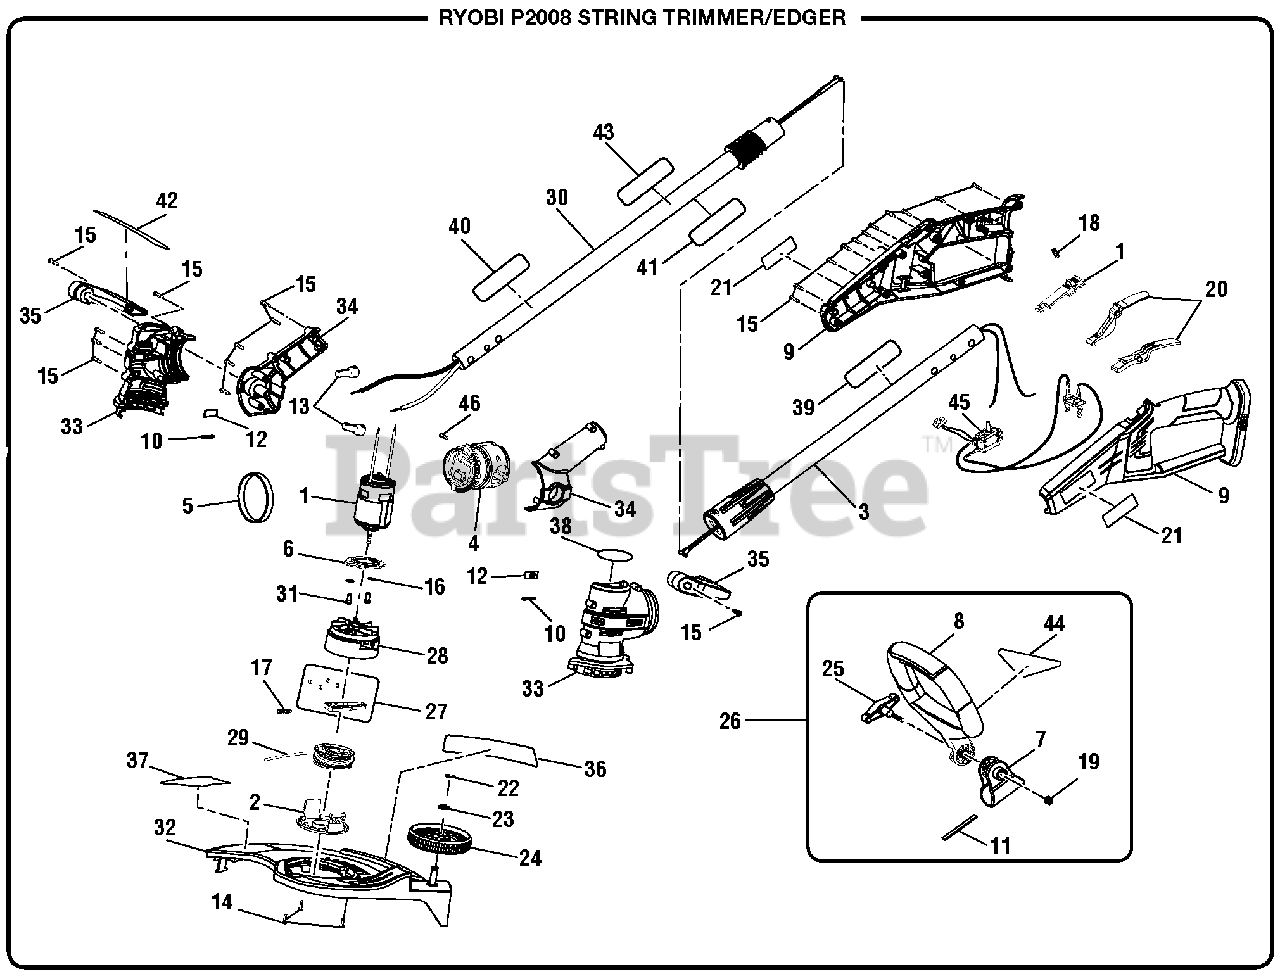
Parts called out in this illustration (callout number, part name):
2	Spool Cap
3	Upper Tube and Wire Assembly
4	Pivot Assembly
5	Plastic Ring
6	Motor Mounting Plate
7	Handle Bracket
8	Front Handle
9	Handle Housing Assembly
10	Rubber Plate (Motor Plate)
11	Rubber Plate (Handle Bracket)
12	Rubber Plate (Motor)
13	Wire Connector
14	Screw (M4 x 12 mm, Pan Hd.)
15	Screw (M4 x 14 mm, T14 Torx Pan Hd.)
16	Lock Washer (M5, OD10 x ID5 x 0.45t))
17	Compression Spring (Internal Tooth)
18	Compression Spring (Trigger)
19	Hex Nut (M6)
20	Switch Trigger and Lock-off Trigger
21	Logo Label
23	Washer (OD16 x ID8.2 x 1.2t)
25	Knob Bolt (M6 x 1 in.)
26	Auxiliary Handle Assembly
27	Slider Assembly
28	Spool Base w/Fan
29	Spool w/Line Assembly
30	Lower Tube Assembly
31	Screw w/Washer (M5 x 11 mm)
32	Guard Assembly
33	Motor Housing Assembly
34	Lower Housing Assembly
35	Adjustment Pedal Assembly
36	Auto Feed No Bump Label (Guard)
37	Adjustable Cutting Width Label
38	Motor Housing Label
39	Data Label
40	Ryobi 18 V Lithium Label
41	Warning Translation Label
42	Step For Edging Label
43	Warning Icon Label
44	Auto Feed No Bump Label (Handle)
45	Switch and Contact Plate Assembly
46	Screw (M3 x 12 mm, Pan Hd.)
